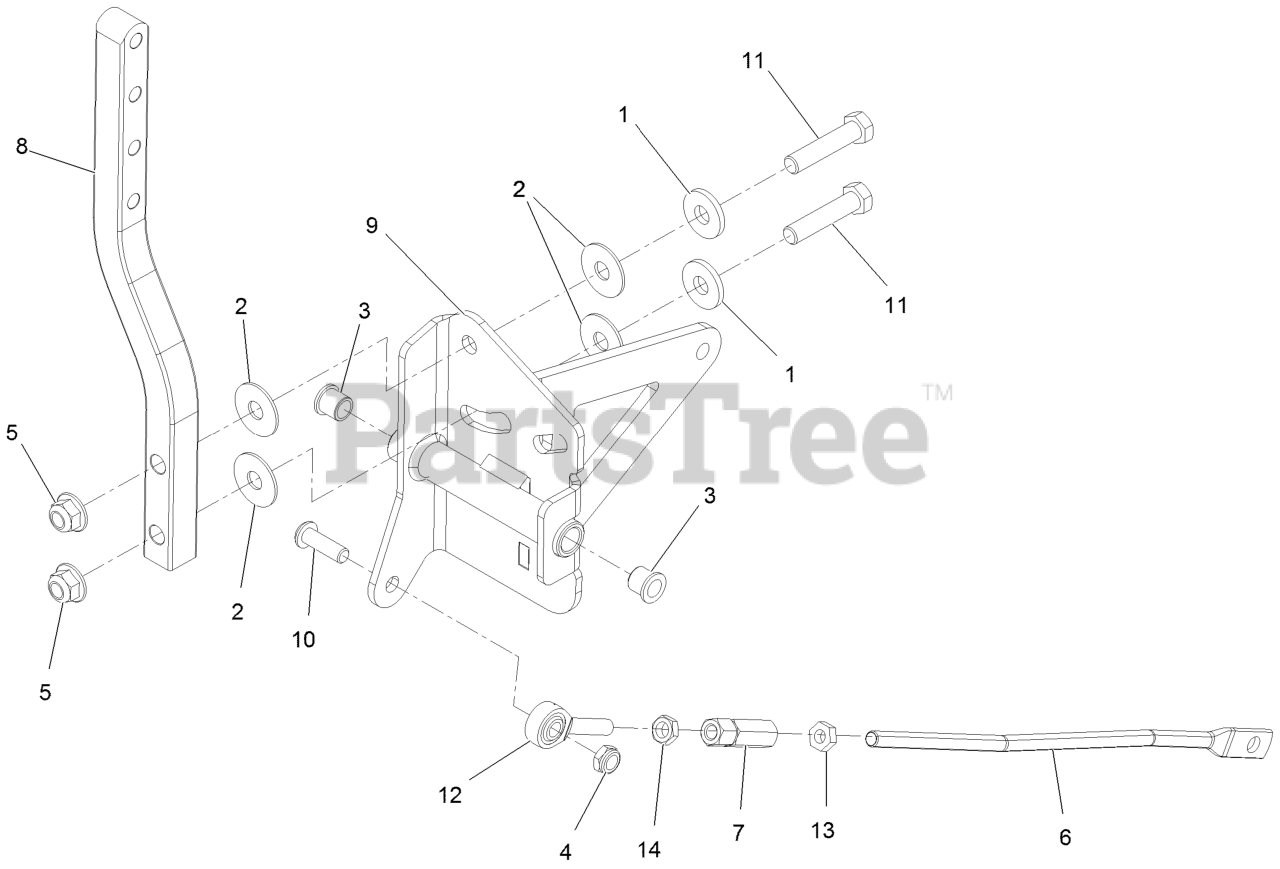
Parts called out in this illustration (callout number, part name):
1	WASHER
2	WASHER-PLASTIC
3	BEARING
4	NUT-LOCK, NI
5	NUT-HF, NI
6	LINK,MOTION CONTROL
7	NUT-ROD ADJUSTMENT
8	ARM-MOTION CONTROL
9	RH CONTROL PIVOT ASM
10	SCREW-HSBH
11	SCREW-HH
12	BEARING-ROD END, LH
13	NUT-JAM
14	NUT-JAM
